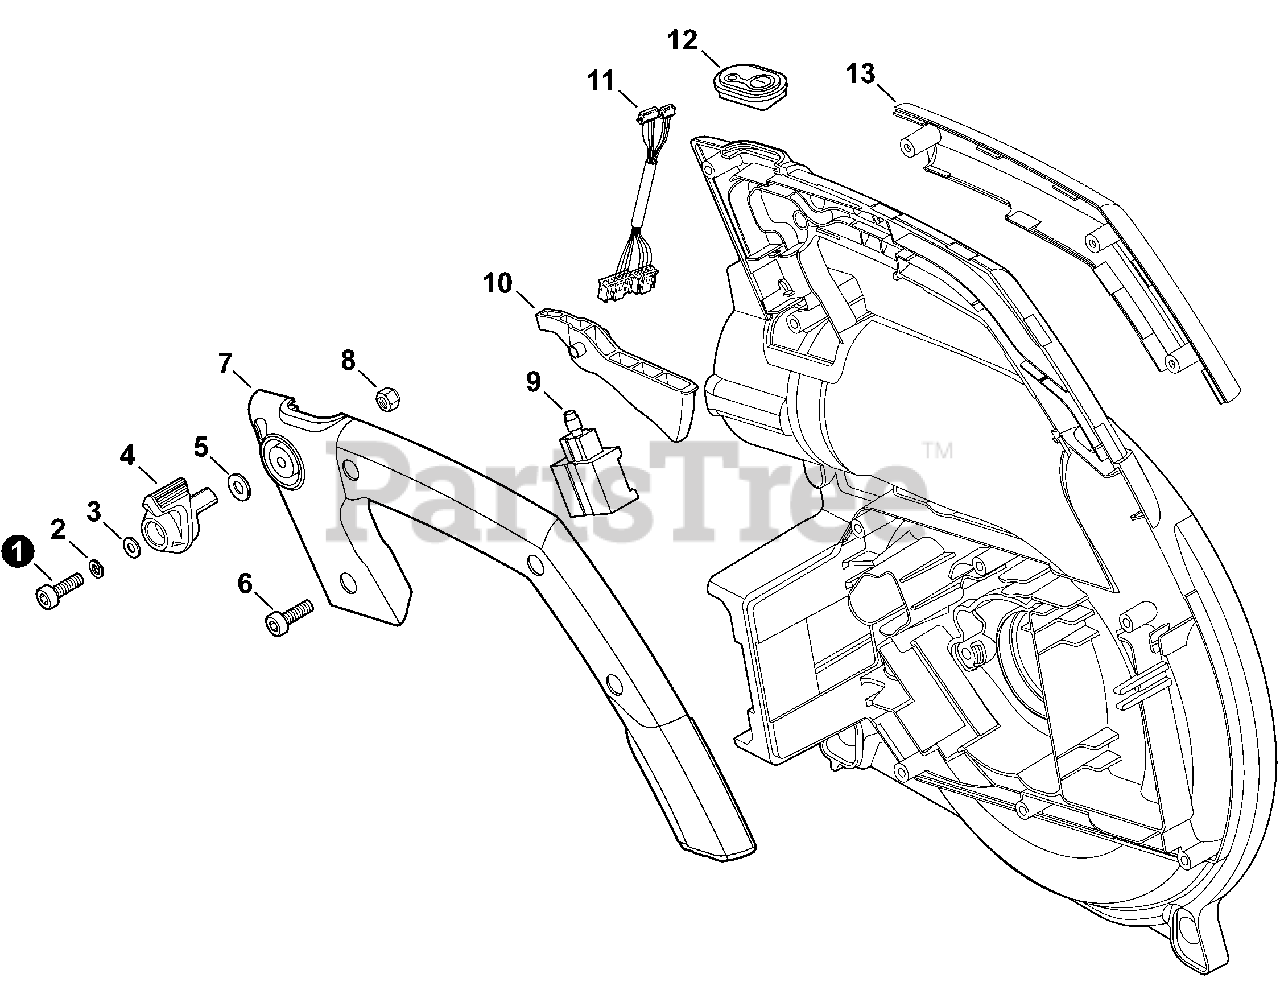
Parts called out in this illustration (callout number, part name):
1	BOLT, TORX 5×25
2	WASHER, SPRING 5
3	WASHER 5.3×10×1
4	LEVER, CRUISE CONTROL
5	WASHER 5.5×12×0.8
6	BOLT, TORX 4×16
7	COVER, HANDLE
8	NUT, LOCK M5
10	TRIGGER
11	LEAD, ON-OFF
12	SWITCH, ON-OFF
13	GRIP, HANDLE
